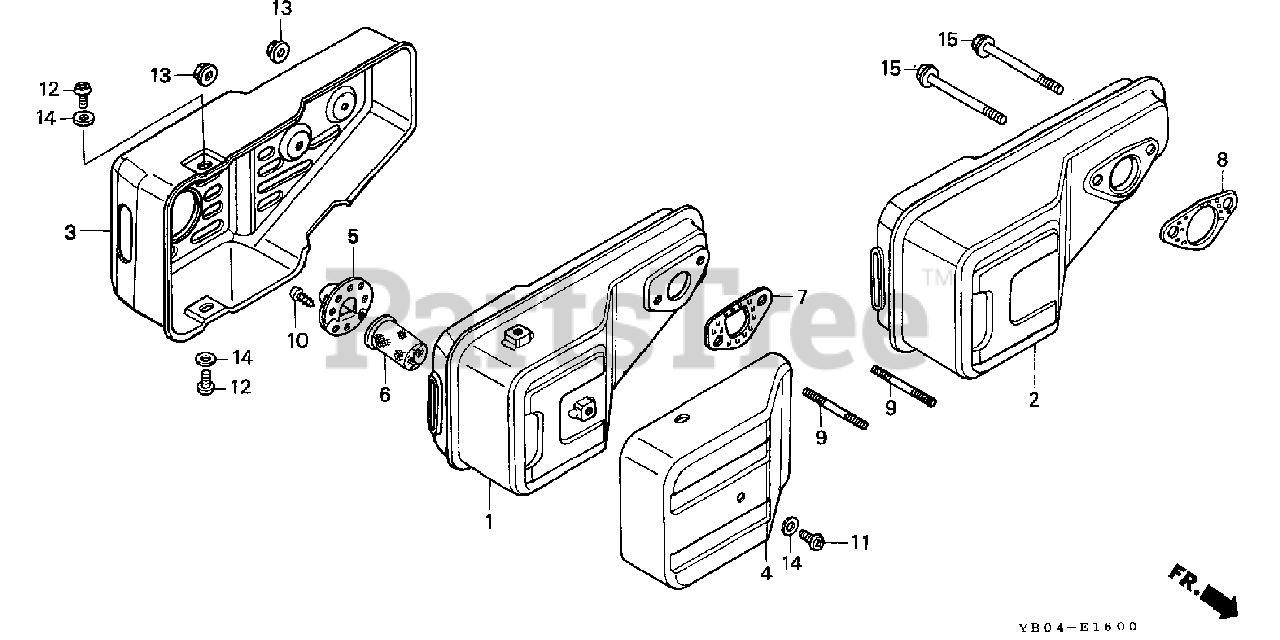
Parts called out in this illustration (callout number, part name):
2	MUFFLER (NOT AVAILABLE)
8	GASKET, MUFFLER (NOT AVAILABLE)
15	BOLT, FLANGE (6X40)
